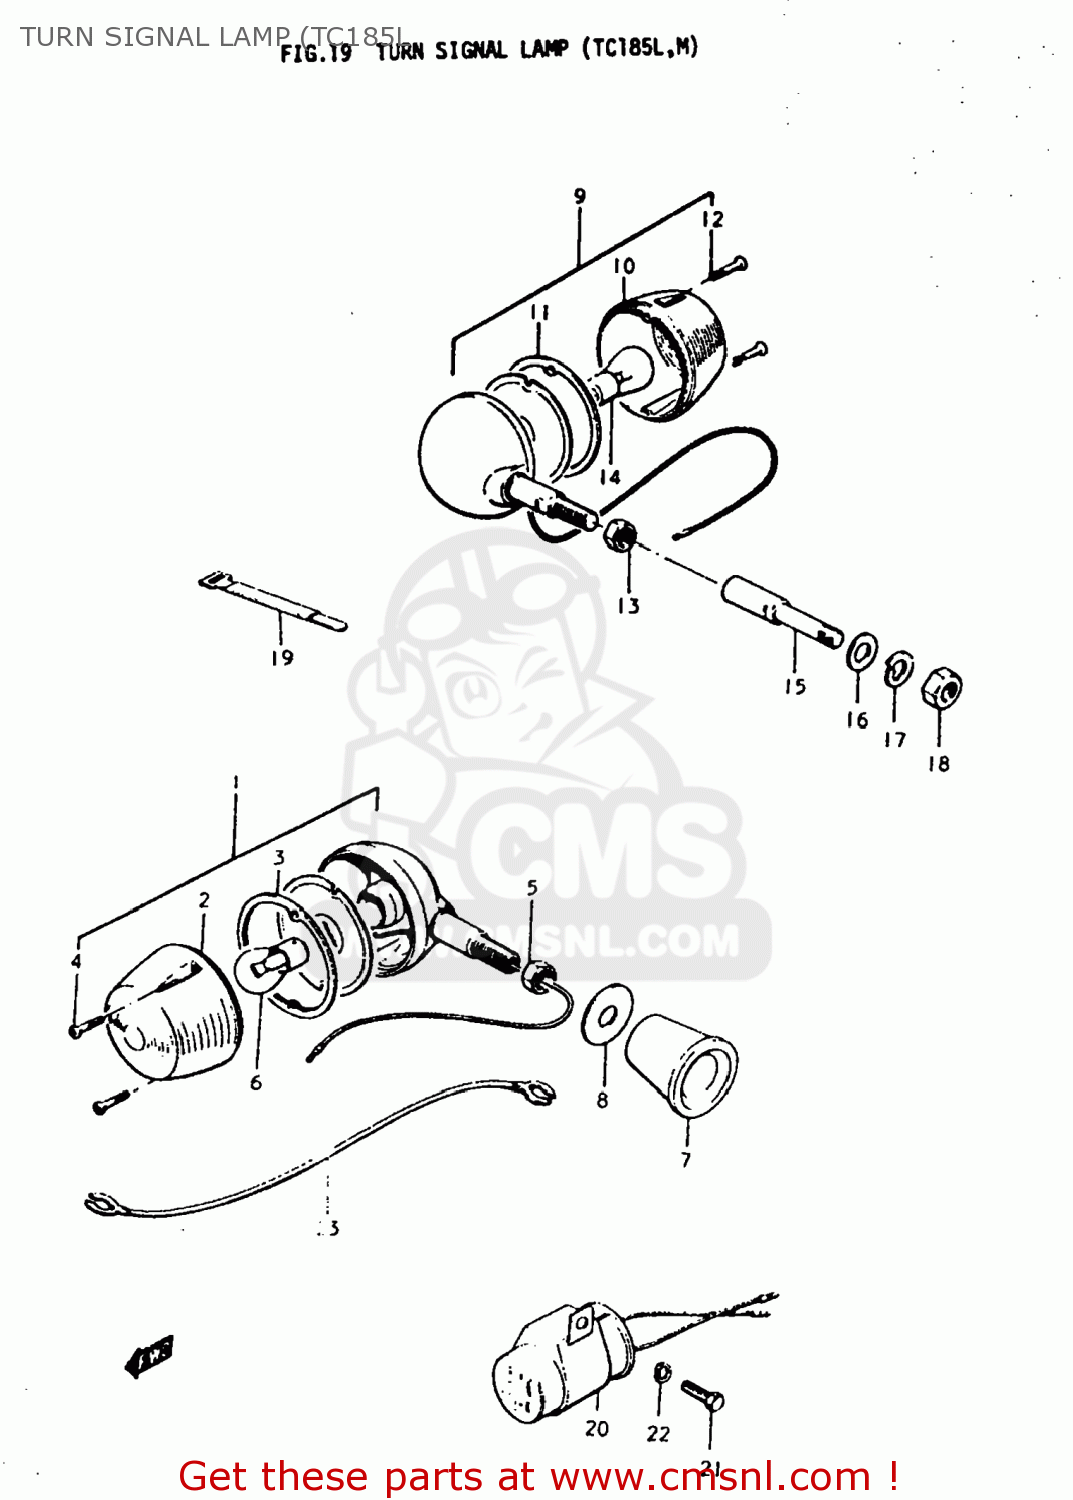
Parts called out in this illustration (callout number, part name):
1	LAMP ASSEMBLY,FRONT TURN SIGNAL
2	LENS,TURNSIGNAL
3	GASKET,TURNSIGNAL LENS (NAS)
4	SCREW
5	NUT
6	BULB(12V23W,STANLEY,A4577A)
7	COVER,FRONT TURN SIGNAL BRACKET
8	WASHER
9	LAMP ASSEMBLY,REAR TURN SIGNAL
10	LENS
11	GASKET,TURNSIGNAL LENS (NAS)
12	SCREW
13	NUT
14	BULB(12V23W,STANLEY,A4577A)
15	STAY,TURN SIGNAL,REAR
16	WASHER
17	LOCK WASHER
18	NUT
19	CLAMP
20	RELAY,TURN SIGNAL
21	BOLT
22	LOCK WASHER
23	WIRE
